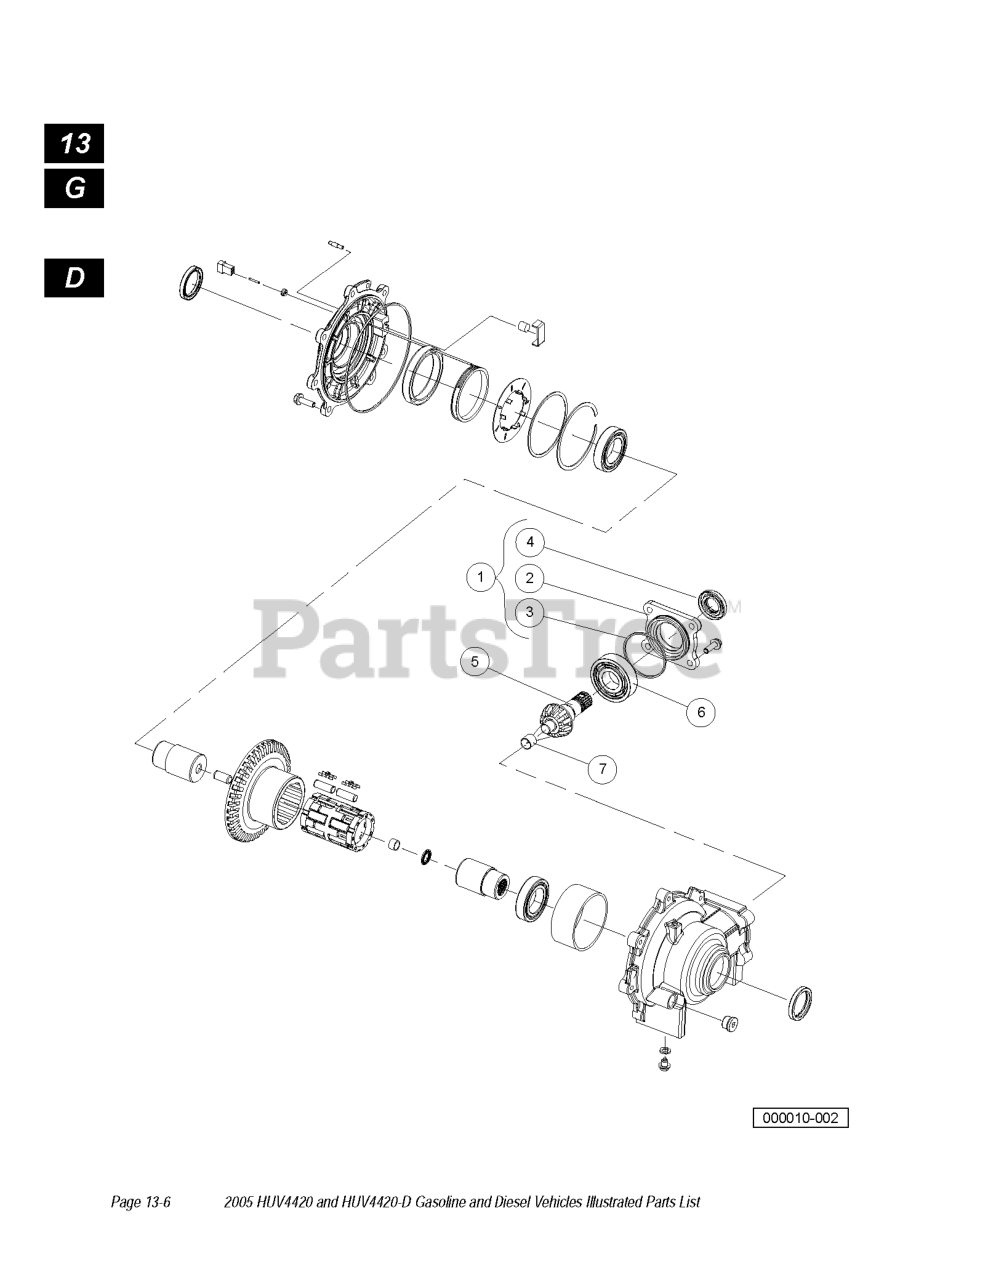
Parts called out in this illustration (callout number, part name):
1	KIT, ASSY, INPUT COVER PLATE
2	COVER, INPUT, MACHINED
5	SHAFT, PINION, MACHINED
6	BEARING, DGBR, 6306-C3
